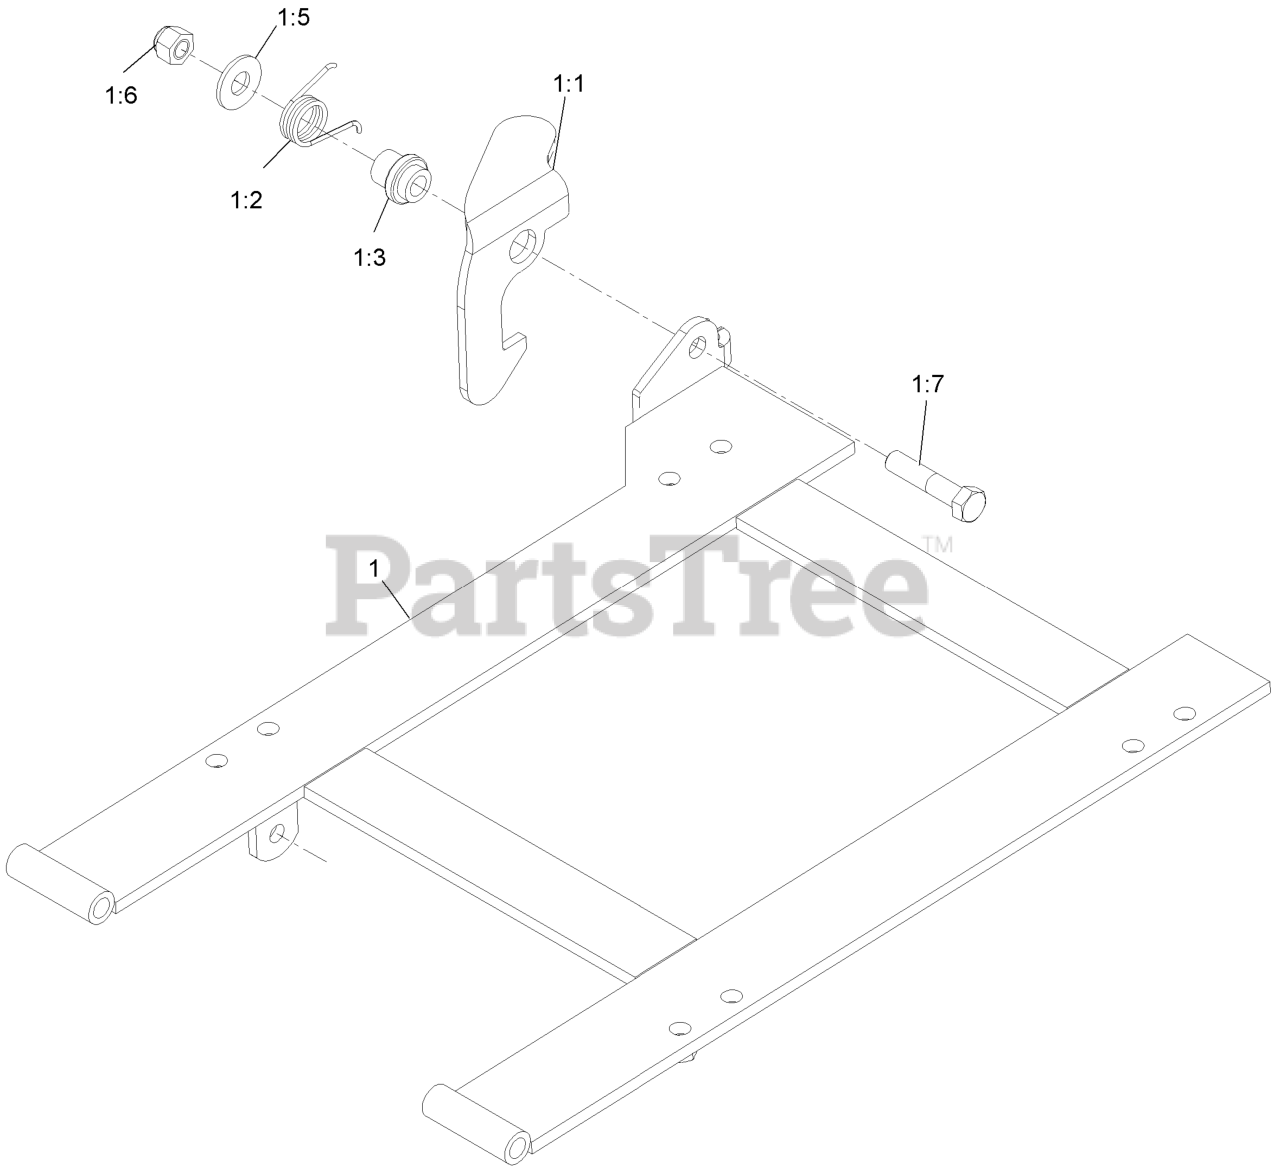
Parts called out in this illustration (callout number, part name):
1	Seat Frame Single Latch ASM
1:1	CATCH-LATCH, SINGLE
1:2	SPRING-TORSION, LATCH
1:3	BUSHING-LATCH, SEAT
1:5	WASHER-FLAT
1:6	NUT-LOCK, NI
1:7	SCREW-HH
